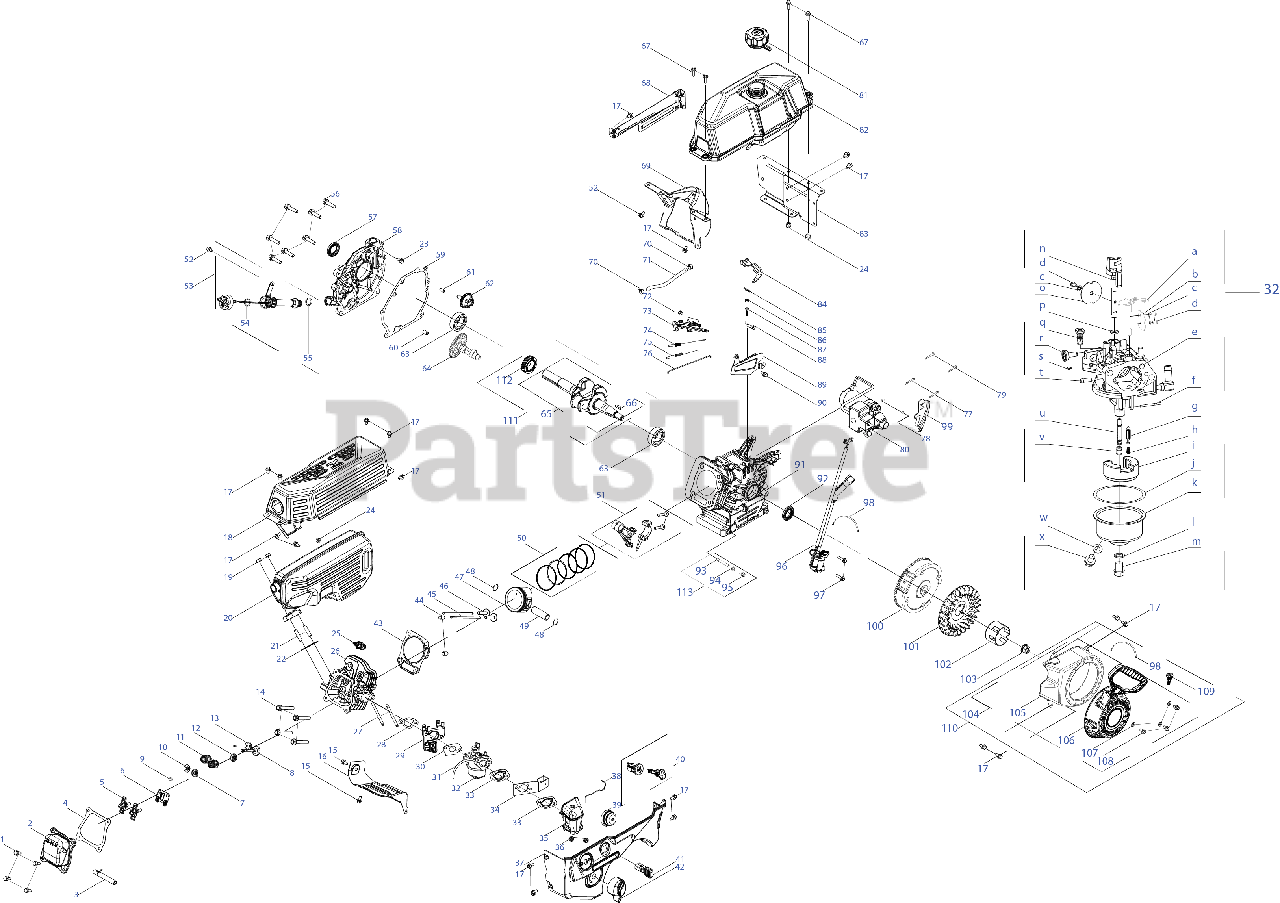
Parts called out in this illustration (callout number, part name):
1	BOLT M6 x 16
2	VALVE COVER
3	BREATHER HOSE
4	VALVE COVER GASKET
5	ROCKER ARM ASSEMBLY
6	ROCKER ARM BASE
7	INTAKE VALVE SPRING RETAINER
8	INTAKE VALVE
9	EXHAUST VALVE ADJUSTER
10	EXHAUST VALVE SPRING RETAINER
11	VALVE SPRING
12	INTAKE VALVE SEAL
13	EXHAUST VALVE
14	BOLT M8-1.25 x 55 GR10.9
15	BOLT M6-1 x 12 GR8.8
16	AIR SHIELD
17	BOLT-M6 x 12
18	MUFFLER GUARD
20	MUFFLER
21	STUD M8-1.25 x 36
22	MUFFLER GASKET
23	SCREW M6-1 x 20 CL5.8
24	HEX NUT
25	SPARK PLUG
26	CYLINDER HEAD
27	STUD M6 x 92
28	CARBURETOR INSULATOR GASKET
29	CARBURETOR INSULATOR
30	CARBURETOR GASKET
31	PRIMER HOSE
32	CARBURETOR ASSEMBLY
33	CARBURETOR GASKET PLATE
34	CHOKE CONTROL
35	HEATER BOX
36	HEX NUT
37	CONTROL PANEL
38	PUSH ROD
40	ENGINE KEY SWITCH ASSEMBLY
41	THROTTLE CONTROL KNOB
42	CHOKE LEVER
43	CYLINDER HEAD GASKET
44	DOWEL PIN
45	PUSH ROD
46	TAPPET
47	PISTON
48	PISTON PIN SNAP RING
49	PISTON PIN
50	PISTON RING SET
51	CONNECTING ROD ASSEMBLY
52	BOLT-M6 x 16
53	DIPSTICK ASSEMBLY
54	DIPSTICK O-RING
55	O-RING 15.8 x 2.5
56	BOLT M8-1.25 x 32 GR5.8
57	OIL SEAL
58	CRANKCASE COVER
59	CRANKCASE COVER GASKET
60	DOWEL PIN
61	DOWEL PIN
62	GOVERNOR GEAR/SHAFT ASSEMBLY
63	BEARING
64	CAMSHAFT
65	CRANKSHAFT
66	FLYWHEEL KEY
67	BOLT-M6 x 22
68	FUEL TANK INSULATOR
69	FRONT FUEL TANK BRACKET
70	HOSE CLAMP
71	FUEL LINE
72	BOLT M6-1 x 12 GR8.8
73	GOVERNOR GEAR BRACKET
74	GOVERNOR SPRING
75	THROTTLE RETURN SPRING
76	GOVERNOR ROD
77	BOLT M6-1 x 32 GR8.8
78	DOWEL PIN
79	BOLT-M4 x 55
80	ELECTRIC STARTER
81	FUEL CAP
82	FUEL TANK
83	FUEL TANK INSULATOR
84	GOVERNOR LEVER
85	COTTER PIN
86	GOVERNOR SEAL
87	O-RING
88	GOVERNOR SHAFT
89	AIR FLOW SHIELD
90	BOLT M6-1 x 10 GR8.8
91	CRANKCASE
92	OIL SEAL
93	OIL DRAIN PIPE
94	WASHER
95	OIL DRAIN PLUG
96	IGNITION MODULE
97	BOLT M6-1 x 25 GR8.8
98	CABLE TIE - 3 x 150
99	LOWER HOUSING
100	FLYWHEEL
101	COOLING FAN
102	STARTER CUP
103	FLYWHEEL NUT
104	RECOIL HOUSING ASSEMBLY
105	BLOWER HOUSING
106	RECOIL STARTER ASSEMBLY
107	RECOIL FLAT WASHER
108	HEX FLANGE BOLT M6-1 x 10 GR8
109	IGNITION KEY
110	RECOIL STARTER
111	CRANKSHAFT
112	DRIVE TIMING GEAR
113	Oil Drain Pipe
